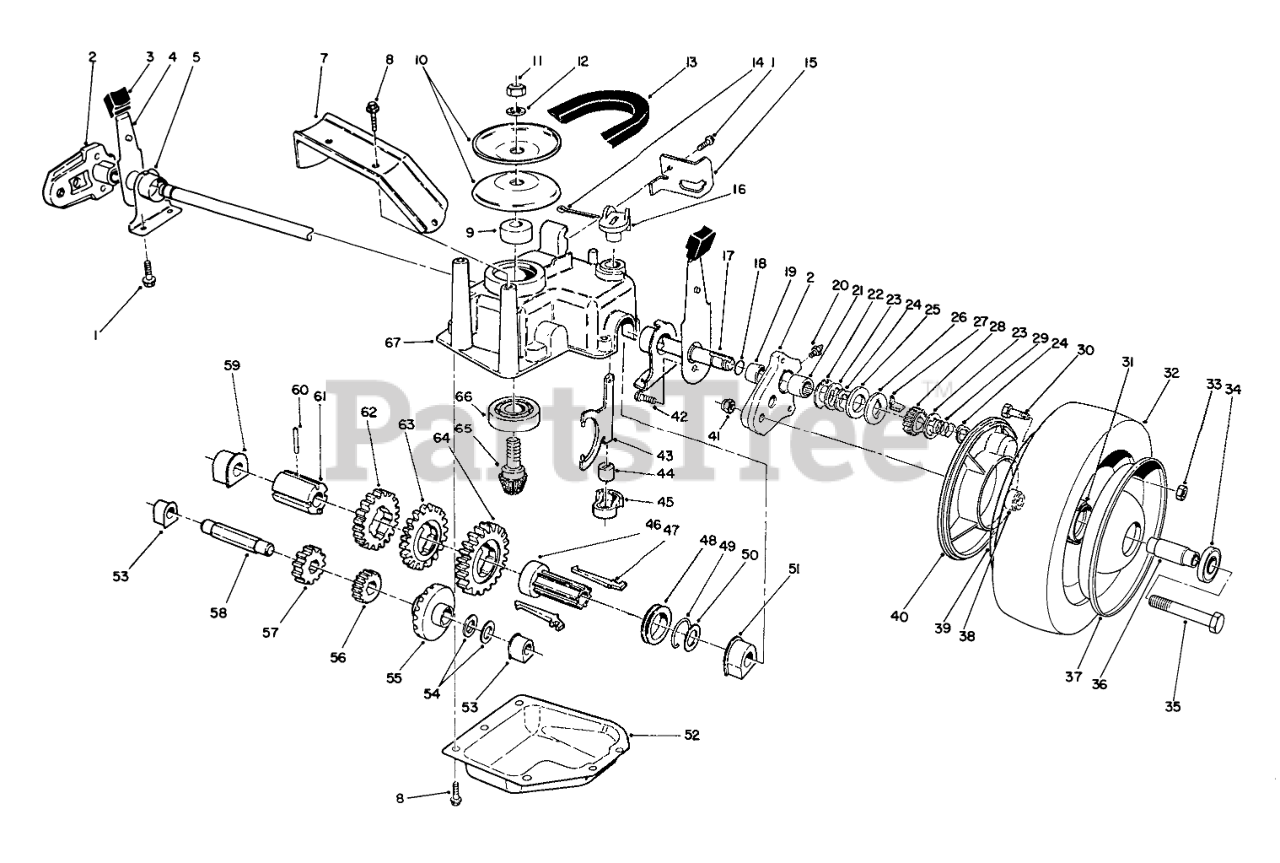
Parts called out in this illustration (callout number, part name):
1	SCREW-HWHTF
2	Pivot Arm Assembly (Incl. Ref. #19-21)
3	KNOB-ARM
4	SPRING ARM ASM
5	CAP-END
7	Bracket-BeltGuide
8	SCREW-HWHTF
9	SPACER
10	Pulley Half
11	NUT-HEX
12	WASHER-FLAT
13	V-BELT
14	PIN-COTTER
15	RETAINER-CABLE
16	LEVER-SHIFT
17	SHAFT-OUTPUT
18	O-RING
19	BUSHING
20	FITTING-GREASE
21	BEARING-ROLLER
22	WASHER-ARM, PIVOT
23	WASHER-THRUST, KEYED
24	RING-CLIP, LOCKING
25	RING-FRICTION
26	WASHER-CLUTCH
27	KEY-ROCKING, LH
28	GEAR-PINION
29	SPRING-COMPRESSION
30	SCREW-HH
31	HUB-BEARING
33	NUT-LOCK, NI
34	BEARING-WHEEL
35	SCREW-HH
36	Spacer-Bearing
37	Wheel-Half
38	SPACER-COVER, WHEEL
39	Wheel-Half
40	WHEEL COVER
41	NUT-LOCK, NI
42	SCREW-HSH, THREAD FORMING
43	YOKE-SHIFT
44	BUSHING-YOKE
45	RETAINER-FORK, SHIFT
46	SLEEVE-KEY, SHIFT
47	KEY-SHIFT
48	COLLAR-SHIFT
49	CLIP-SPRING
50	WASHER-PLAIN
51	BUSHING-OUTPUT
52	Cover-Gearcase
53	BUSHING
54	WASHER-THRUST
55	Gear-Bevel
56	PINION-20T
57	PINION-25T
58	SHAFT-INTERMEDIATE
59	BUSHING
60	PIN-SPRING
61	SLEEVE-GEAR
62	GEAR-39T
63	GEAR-44T
64	GEAR-49T
65	Gear-Pinion
66	BEARING-BALL
67	CASE-GEAR, UPPER
